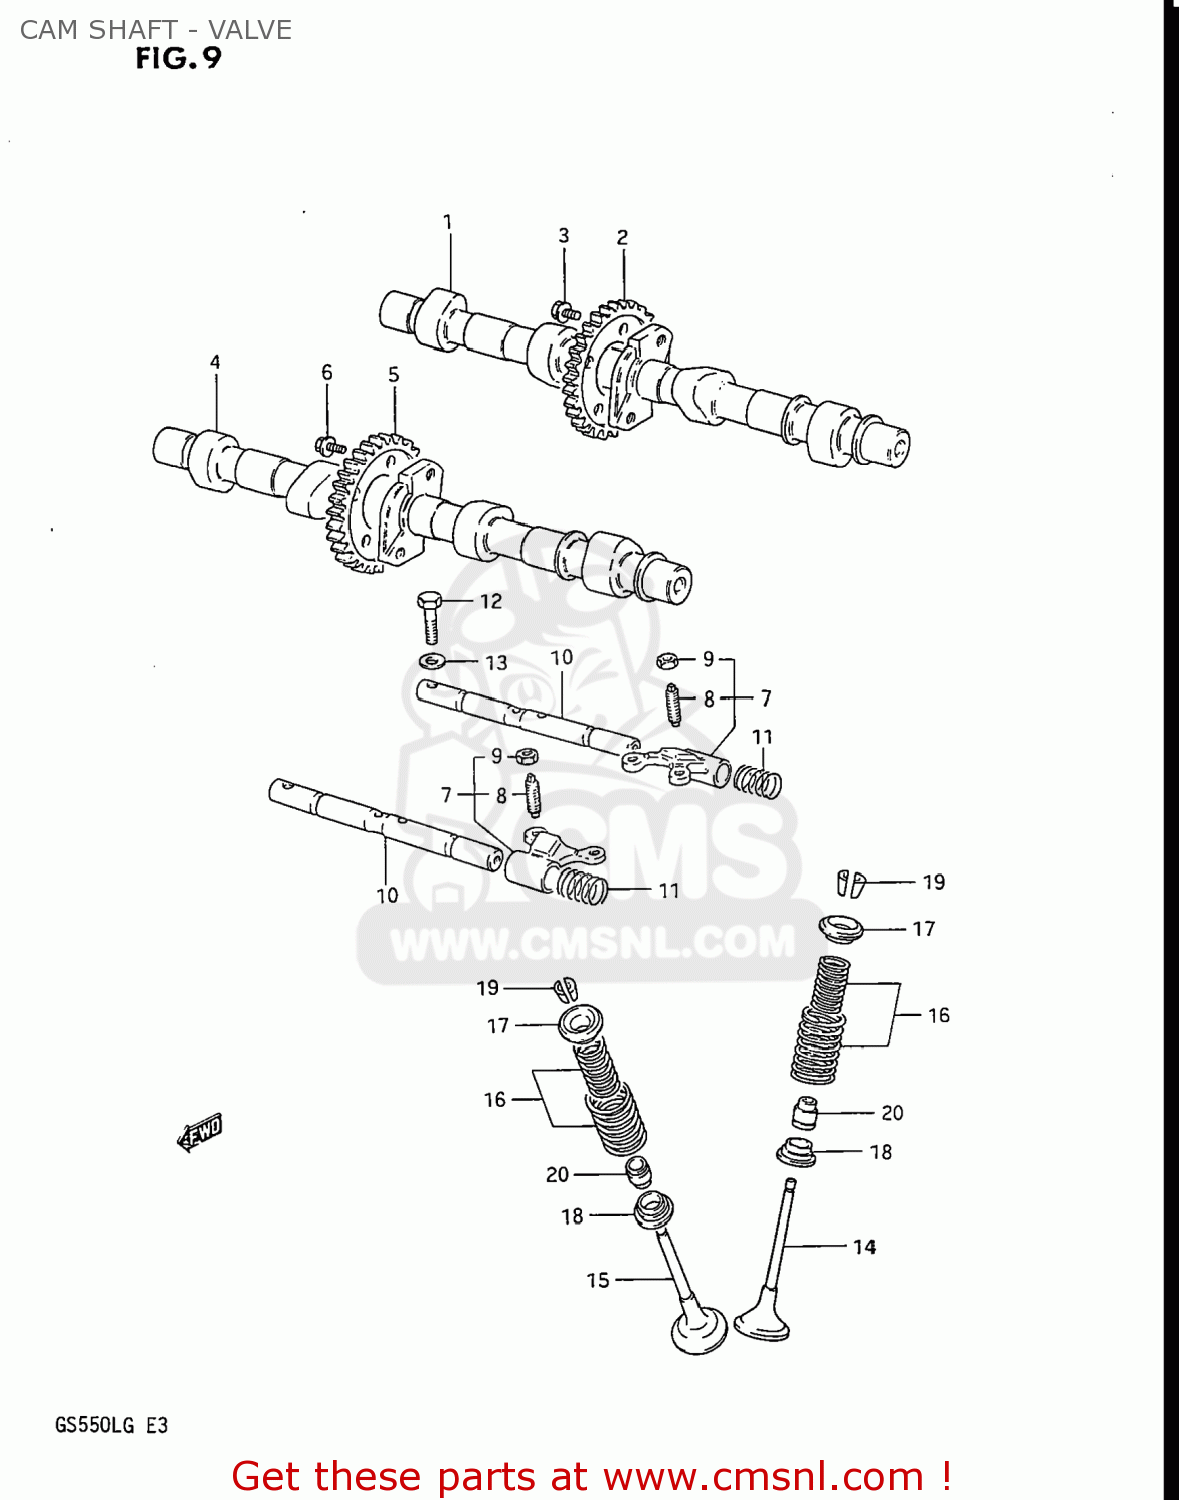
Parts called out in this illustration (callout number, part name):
1	CAMSHAFT,INTAKE
2	SPROCKET,INTAKE CAMSHAFT
3	BOLT(7X11)
4	CAMSHAFT,EXHAUST
5	SPROCKET,INTAKE CAMSHAFT
6	BOLT(7X11)
7	ARM,VALVE ROCKER
8	SCREW,TAPPET ADJUSTING
9	NUT,ADJUSTING
10	SHAFT,VALVE ROCKER
11	SPRING
12	BOLT
13	WASHER, LOWER
14	VALVE,INTAKE
15	VALVE,EXHAUST
16	SPRING SET,VALVE
17	RETAINER,VALVE SPRING
18	SEAT,VALVE SPRING
19	COTTER,VALVE
20	SEAL,OIL(5X10.5X8.4)
